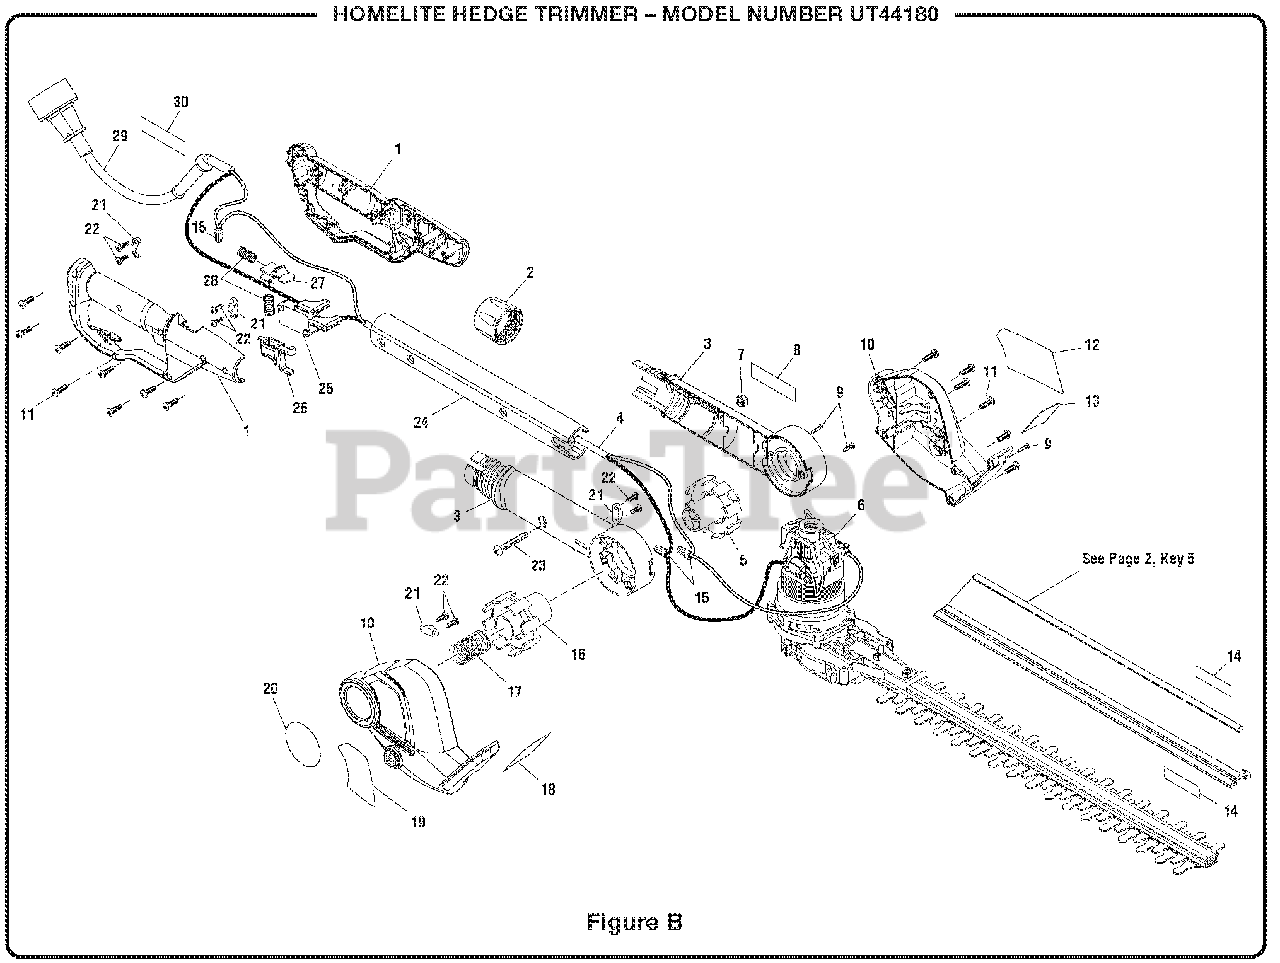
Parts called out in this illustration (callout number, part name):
1	Handle Assembly
3	Pivot Housing Assembly
4	Spring Cord Assembly
5	Pivot Button
6	Motor w/Blade Assembly
7	Lock Nut (M6)
9	Screw (M2.9 x 12 mm)
10	Motor Housing Assembly
11	Screw (M4 x 14 mm)
13	Left Danger Label
14	Deflector Warning Label
16	Pivot Lock
17	Compression Spring
18	Right Danger Label
20	Pivot Label
21	Cord Clamp
22	Screw (M3.5 x 12 mm)
23	Screw (M6 x 41 mm)
26	Switch Trigger
27	Lock Off Button
28	Compression Spring
29	Power Cord Assembly
30	Cord Warning Label
